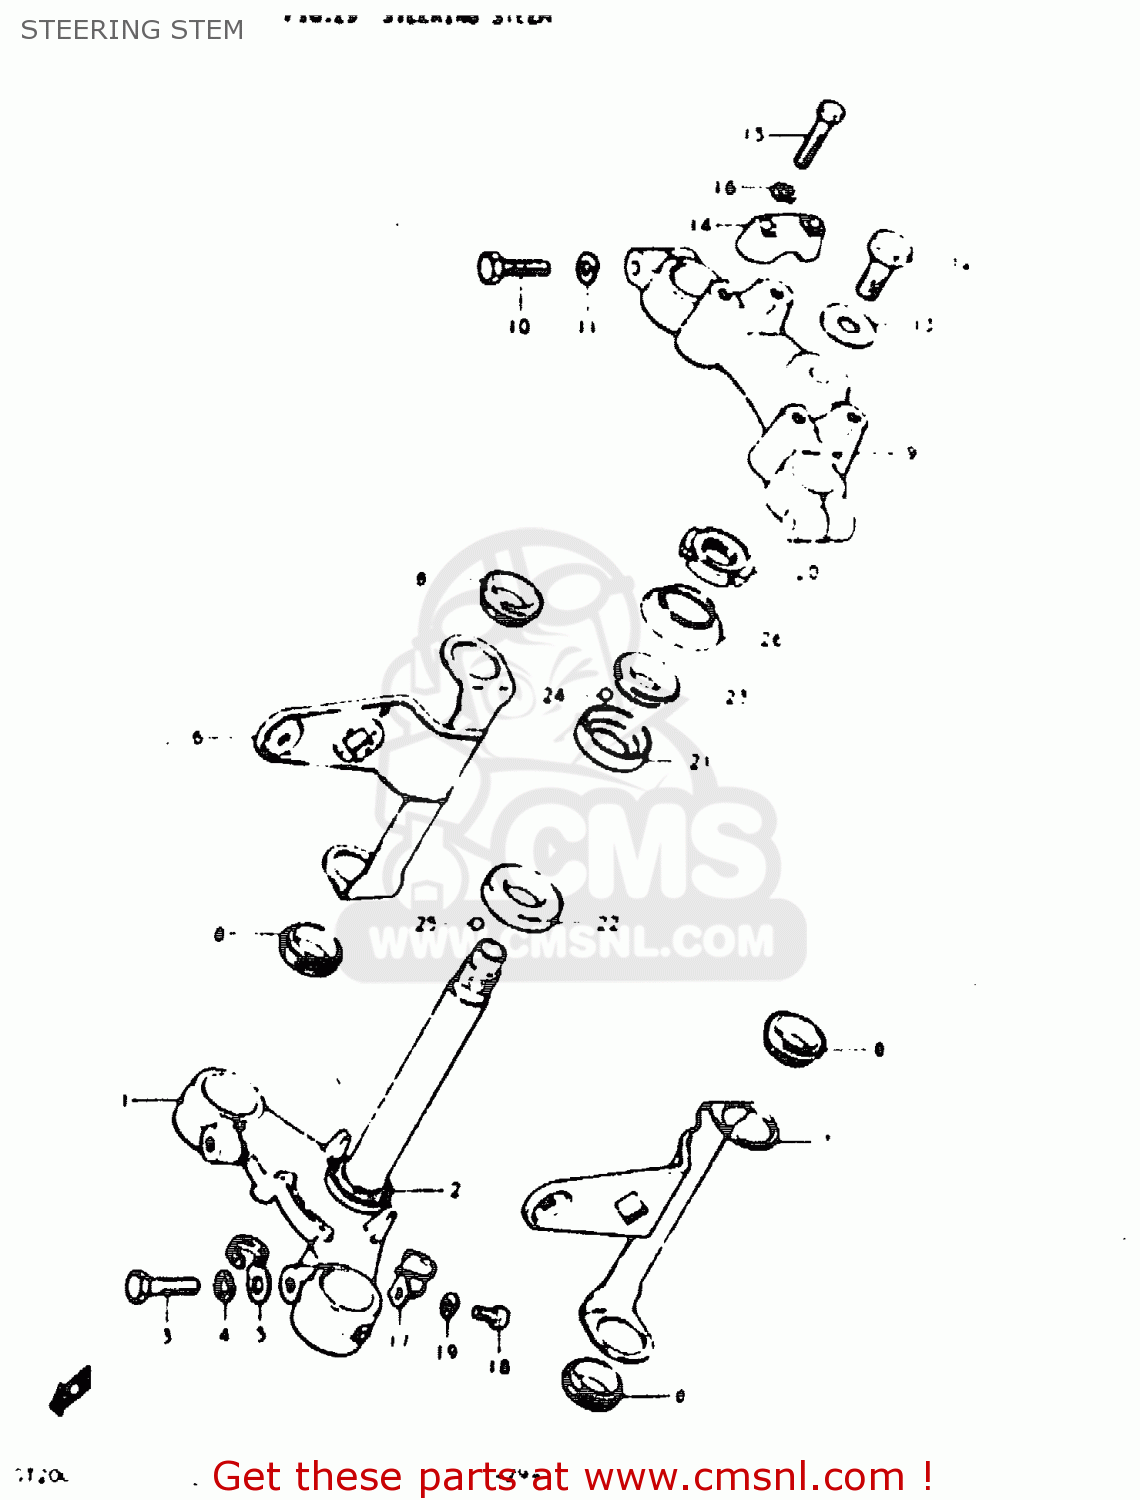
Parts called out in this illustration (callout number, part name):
1	STEERING STEM
2	RACE,STEERING OUTER LWR
3	BOLT,FR FORK LWR(12X33)
4	WASHER,LOCK 12
5	CLIP
6	BRACKET, HEADLAMP RH
7	BRACKET, HEADLAMP LH
8	CUSHION
9	HEAD,STEERING STEM
10	BOLT,FORK INNER TUBE F
11	LOCK WASHER
12	BOLT,FORK INNER TUBE
13	WASHER
14	HOLDER, HANDLEBAR
15	BOLT
16	LOCK WASHER
17	NUT, STEERING STEM
18	SCREW
19	WASHER,LOCK
20	NUT,STEERING STEM(25X44X10)
21	RACE,STEERING INNER UPR
22	LACE,STEERING INNER LWR
23	RACE,STEERING OUTER UPR
24	BALL
25	BALL
26	DUST SEAL
